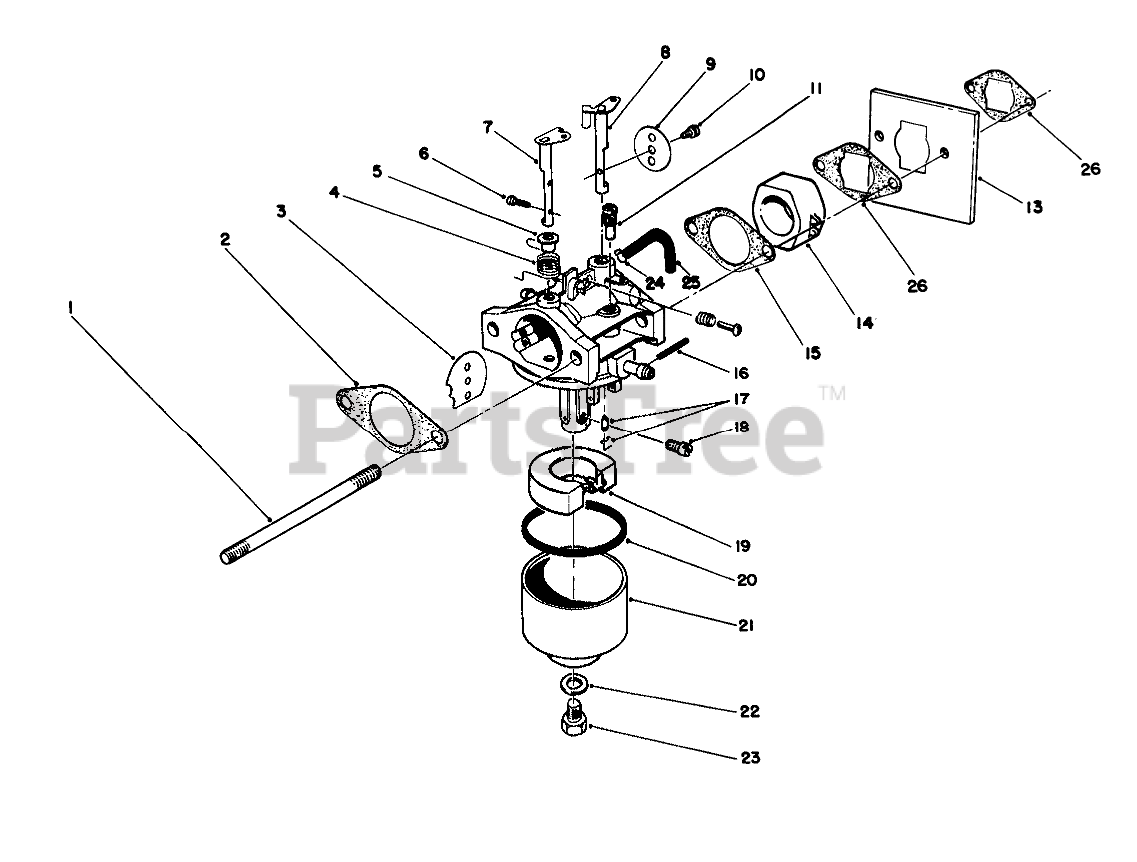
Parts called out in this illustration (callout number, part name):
1	STUD-CARBURETOR
2	GASKET-AIR CLEANER
3	PLATE
4	SPRING
5	BUSHING
6	SCREW
7	SHAFT-CHOKE
8	SHAFT
9	PLATE
10	Screw-Throttle
11	PILOT JET
13	SHIELD-CARBURETOR
14	INSULATOR-CARBURETOR
15	GASKET-CARB
16	Pin
17	NEEDLE
18	JET-MAIN
19	FLOAT
20	GASKET
21	BOWL - FLOAT
22	GASKET
23	SCREW
24	CLAMP
25	VENT TUBE
26	GASKET
